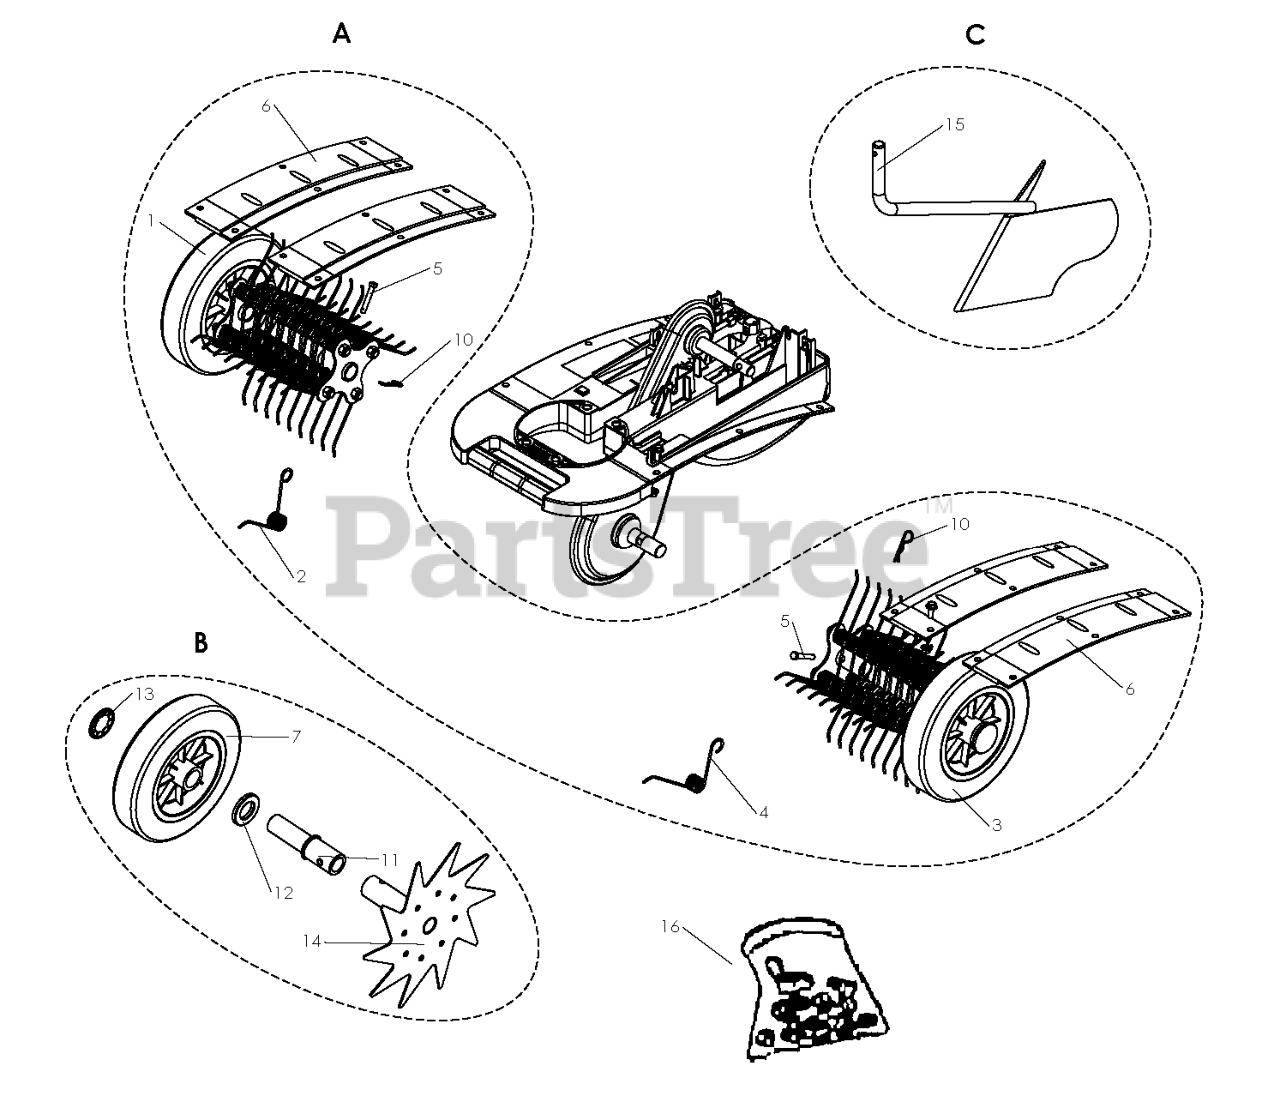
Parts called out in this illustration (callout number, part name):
1	LAWNRAKE
2	LAWNRAKE
3	LAWNRAKE
4	SPRING
5	PIN
7	WHEEL
10	COTTER PIN
11	EDGER
12	WASHER
13	WASHER
14	EDGER ATTACHMENT
16	SCREW KIT
